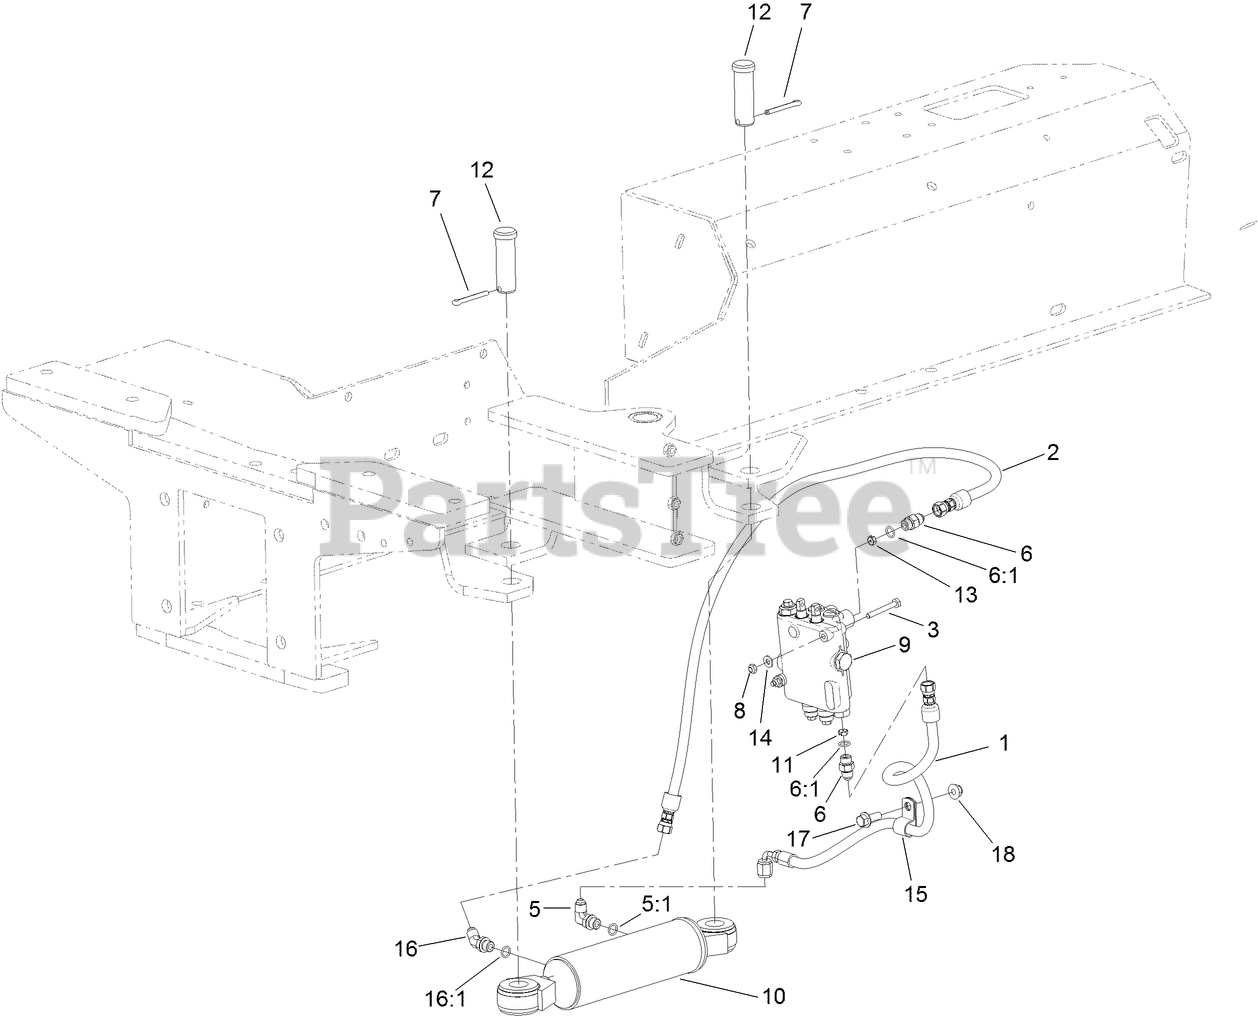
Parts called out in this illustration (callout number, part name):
1	HOSE ASM
2	HOSE ASM
3	SCREW-HH
5	FITTING-ELBOW, 90 DEG
5:1	O-RING
6	FITTING-STRAIGHT
6:1	O-RING
7	PIN-COTTER
8	NUT-LOCK, CONE
9	HYD STEERING VALVE ASM
10	HYD CYLINDER ASM
11	PLATE-ORIFICE
12	PIN-CLEVIS
13	PLATE-ORIFICE
14	WASHER-FLAT
15	CLAMP-R
16	FITTING-ELBOW, 45 DEG
16:1	O-RING
17	SCREW-HHF
18	NUT-HF, NI
